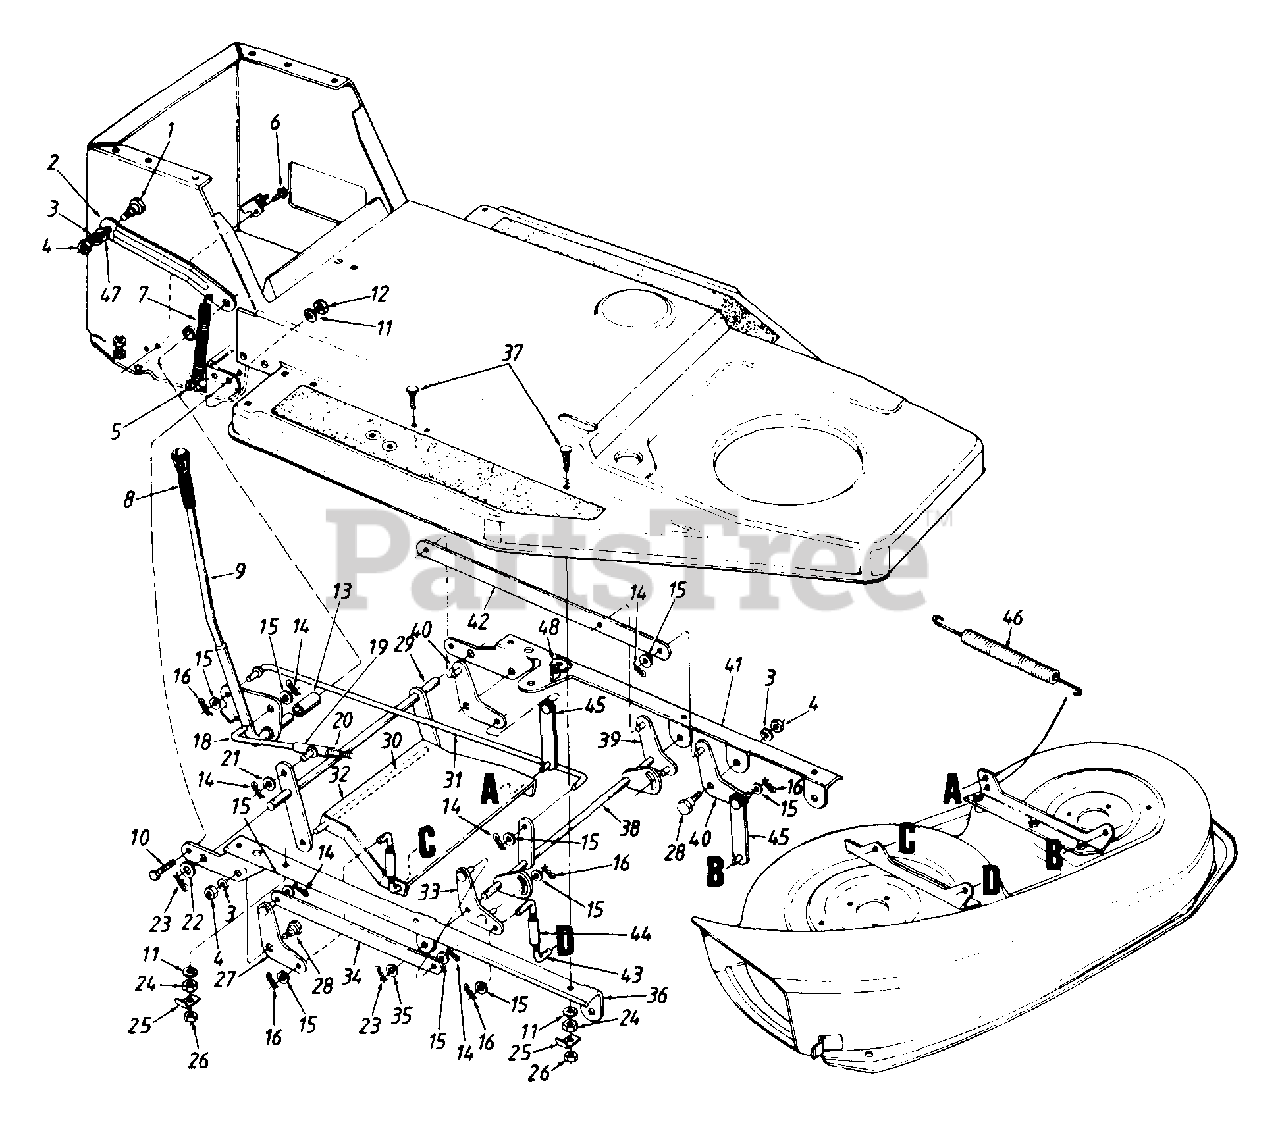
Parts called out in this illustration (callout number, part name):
1	Shld. Bolt .5" Dia. x .34" Lg.
4	Hex Nut 3/8-16 Thd.
5	Hex Bolt 1/4-28 x 1.25" Lg.
6	Hex Wash. Hd. TT-Tap Scr. 1/4-20 x .5" Lg.
7	Ext. Spring
9	Deck Lift Handle Ass'y.
10	Hex Wash. TT-Tap Scr. 5/16-18 x .62" Lg.
11	L-Wash. 5/16" I.D.
12	Hex Nut 5/16-18 Thd.
13	Spacer 5/8" I.D. x .78" O.D.
14	Cot-Pin 3/32" Dia. x .75" Lg.
15	Fl-Wash..406" I.D. x .75" O.D.
16	Internal Cot-Pin 5/16" Dia.
18	Deck Engagement Rod
19	Pivot Sleeve Ass'y.
20	Hex L-Nut 3/8-16 Thd.
21	Thrust Washer .382" I.D.
22	Fl-Wash..635" I.D. x .93" O.D.
23	Cot-Pin 1/8 Dia. x 1.25" Lg.
24	Hex Nut 5/16-24 Thd.
25	Harness Retainer
26	Hex Cent. L-Nut 5/16-24 Thd.
27	Deck Pivot Brkt. Ass'y.- R.H. Rear
28	Shld. Bolt .625" Dia. x .170" Lg.
31	Deck Lift Rod
32	Deck Stabilizer Brkt.
44	Adj. Lift Link Ass'y.
45	Deck Lift Link
46	Deck Spring 10.33" Lg.
47	Fl-Wash..531" I.D. x .94" O.D.
